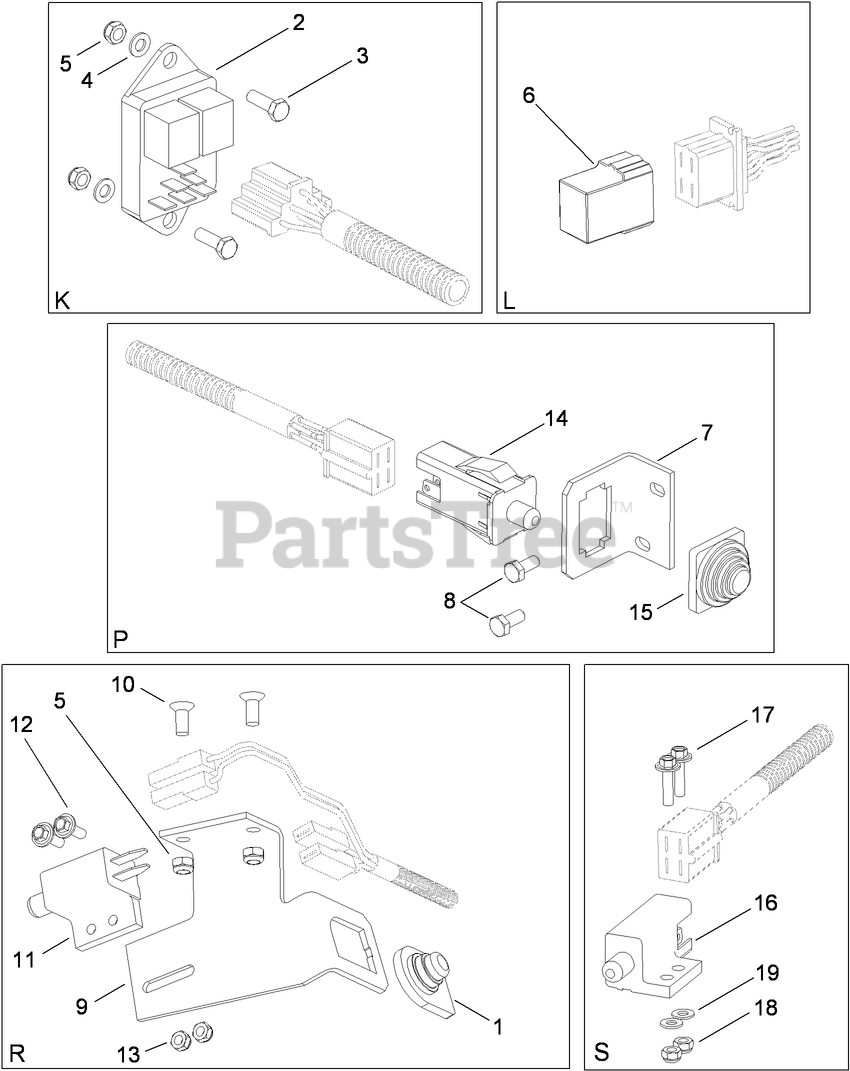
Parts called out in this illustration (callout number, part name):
1	COVER-PROTECTIVE
2	MODULE-CLUTCH
3	SCREW-HH
4	WASHER
5	NUT-LOCK
6	CIRCUIT-MEMORY
7	Holder-Switch
9	HOLDER-SWITCH
11	SWITCH-POLE, SINGLE
13	NUT-HEX
14	SWITCH-DELTA
15	Cover-Switch
16	Switch-Delta
18	NUT-LOCK
19	WASHER
